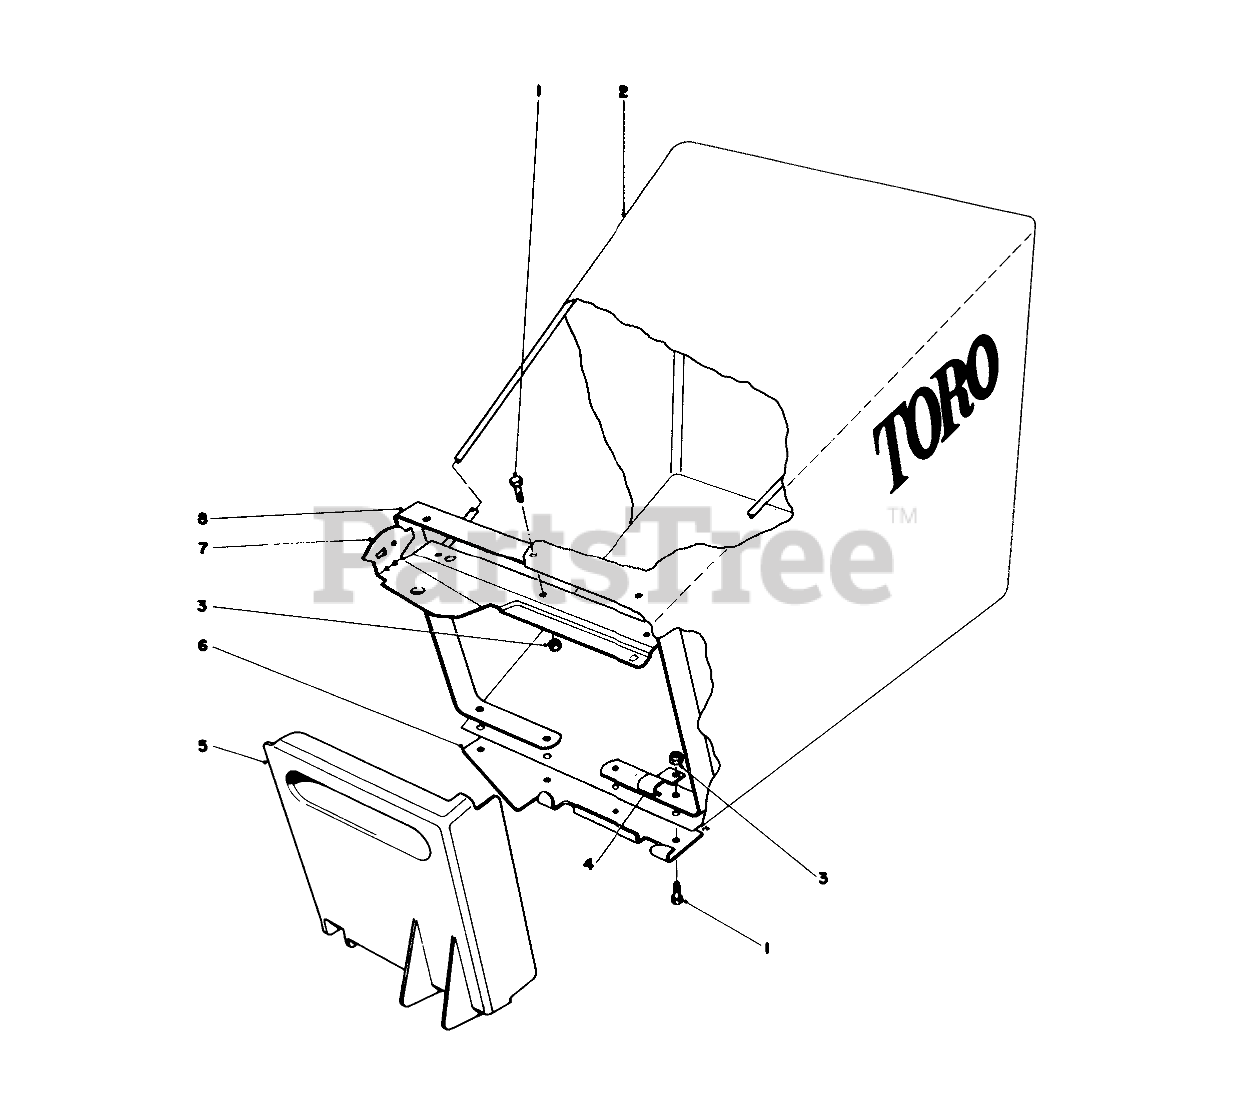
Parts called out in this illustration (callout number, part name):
1	SCREW-HWH
2	REPLACMNT BAG 44-0530
3	NUT-LOCK, SIDE
4	SUPPORT BRACKET
5	BAG DOOR
6	DOOR BRACKET
7	BAG FRAME WA
8	LOWER BAG FRAME
